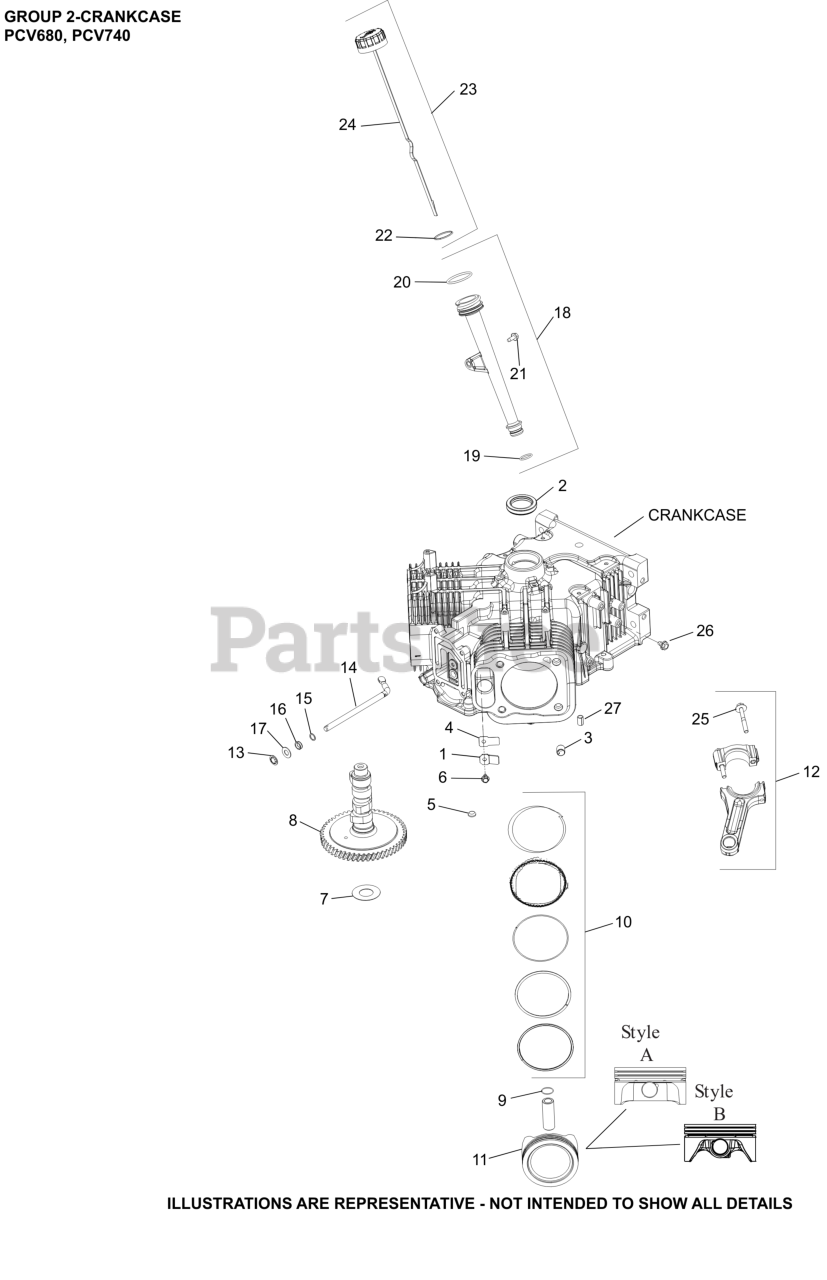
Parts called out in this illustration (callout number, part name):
1	RETAINER, BREATHER REED
2	SEAL, OIL (HELIX LIP)
3	PIN, LOCATING
4	REED, BREATHER
5	PLUG, CUP
6	SCREW, FLG THD FRM M5X.8X10
8	KIT, CAMSHAFT
9	RETAINER, PISTON PIN
10	RING SET(STD)STYLE B-1.2mm Tp RING THICK
10	RING SET(.08)STYLE B-1.2mm RING THICK
10	RING SET(.25)STYLE B-1.2mm Tp RING THICK
10	RING SET(.50)STYLE B-1.2mm Tp RING THICK
11	KIT,PSTN/RNG STYLE B(STD)
11	KIT,PSTN/RNG STYLE B(.08)
11	KIT,PSTN/RNG STYLE B(.25)
11	KIT,PSTN/RNG STYLE B(.50)
12	ROD, ASSEMBLY CONNECTING
13	RETAINER, RING
15	WASHER, FLAT 11/32"
16	SEAL, GOVERNOR CROSS SHAFT
17	WASHER, FLAT 9 MM
18	TUBE ASSEMBLY
19	O-RING, LOWER OIL FILL TUBE
20	O-RING, UPPER OIL FILL TUBE
21	SCREW, FLG THD FRM M5X0.8X13
22	O-RING, DIPSTICK
23	KIT, OIL FILL CAP (YELLOW)
24	DIPSTICK, ASSY
25	KIT, ROD BOLTS-(#25086677S)
NI	SHAFT, GOVERNOR CROSS
